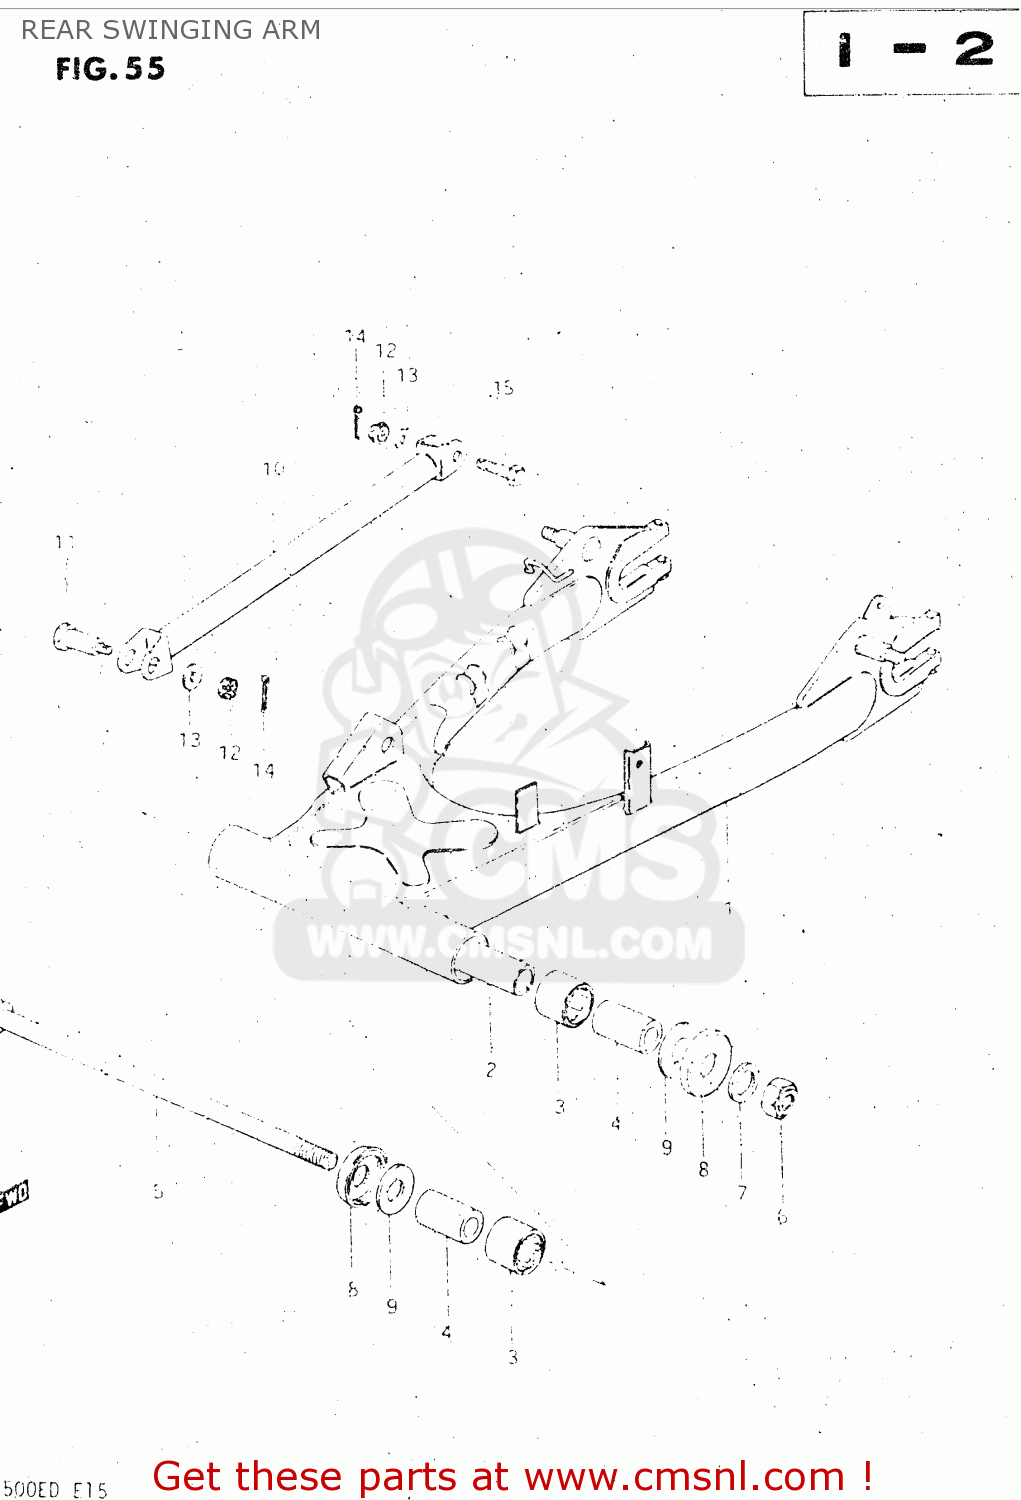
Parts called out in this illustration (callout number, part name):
1	ARM,REAR SWING
2	SPACER,RR SWGARM PIVOT CTR
3	BEARING(22X29X30)
4	SPACER,RR SWGARM PIVOT
5	SHAFT,REAR SWING ARM
6	NUT 14MM
7	WASHER
8	CVR,RR SWGARM DUST SEAL(OD:40)
9	WASHER(14.2X34X1)
10	TORQUE LINK,REAR
11	BOLT
12	NUT
13	WASHER
14	PIN 20X20
15	BOLT(10X39)
